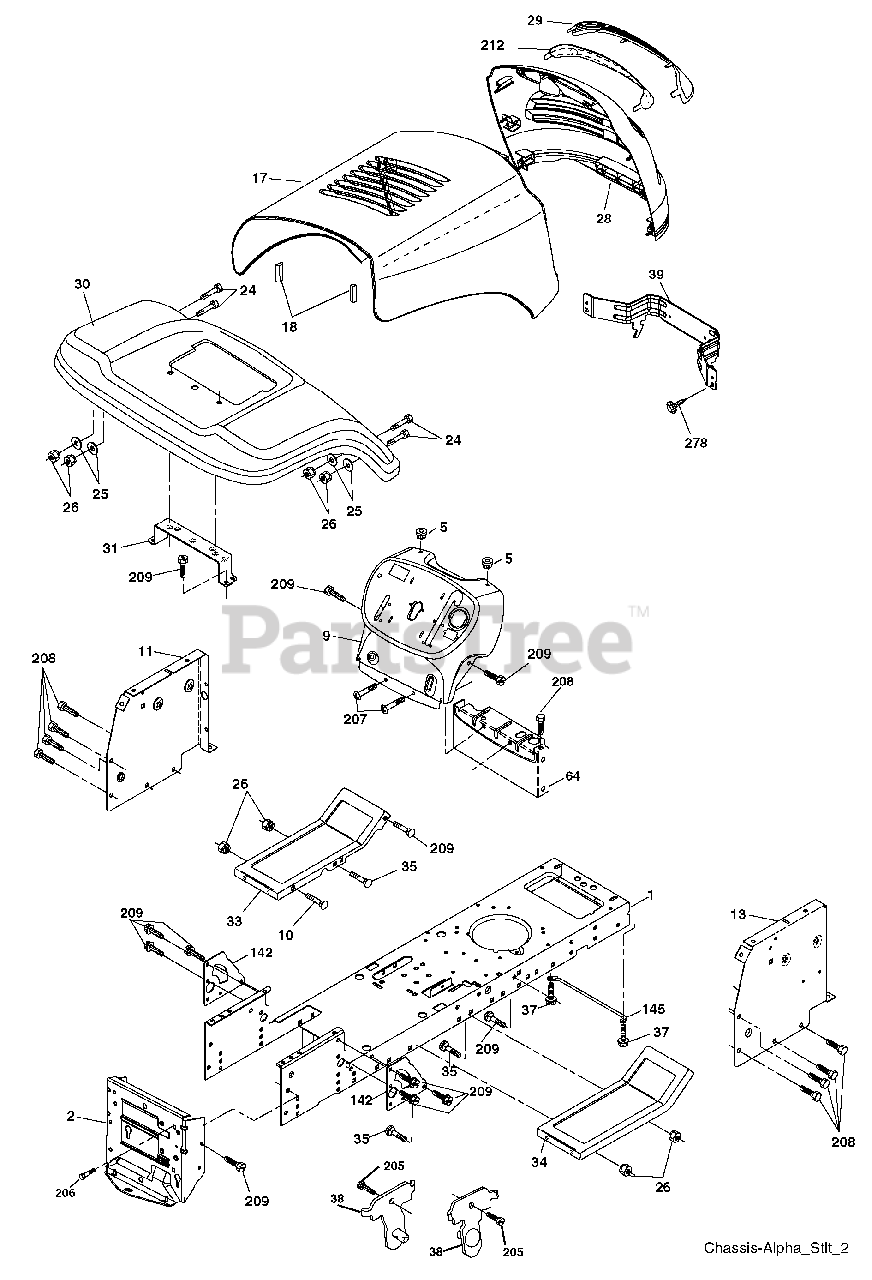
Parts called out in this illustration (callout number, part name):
1	Chassis
2	Drawbar, Stretch
5	Bumper, Hood/Dash
9	Dash
10	Bolt, Carriage 3/8-16 x 1
11	Panel Dash LH
13	Panel Slkscr Dash RH
14	Screw Thdrol 3/8-16 x 1/2
17	Hood
18	Bumper Hood
26	Nut Lock Hex w/Ins 3/8-16 unc
28	Grille/Lens Asm
29	Lens Grille Basic Bar
31	Bracket Fender Repl 109873X
37	Screw Thdrol 5/16-18 x 1/2 TYT
38	Bracket Asm. Pivot Mower
39	Bracket Pivot
60	Bolt Carr 3/8-16 x 3/4
64	Dash Lower
74	Nut 3/8-16 Center Lock
142	Plate Reinforcement
143	Bracket Swaybar Chassis
144	Bracket Footrest
145	Rod Pivot Chassis/Hood
206	Bolt Shoulder 5/16-18
207	Screw Thdrol 5/16-18 x 1/2
208	Screw Thdrol 3/8-16 x 1/2
209	Screw Hex Wsh Thdrol 3/8-16
212	Insert Lens Refl ect
278	Screw 10 x 3/4 Single Lead-Hex
278	Plug Button Blk 359 Dia Choke
278	Plug Dome Plastic
